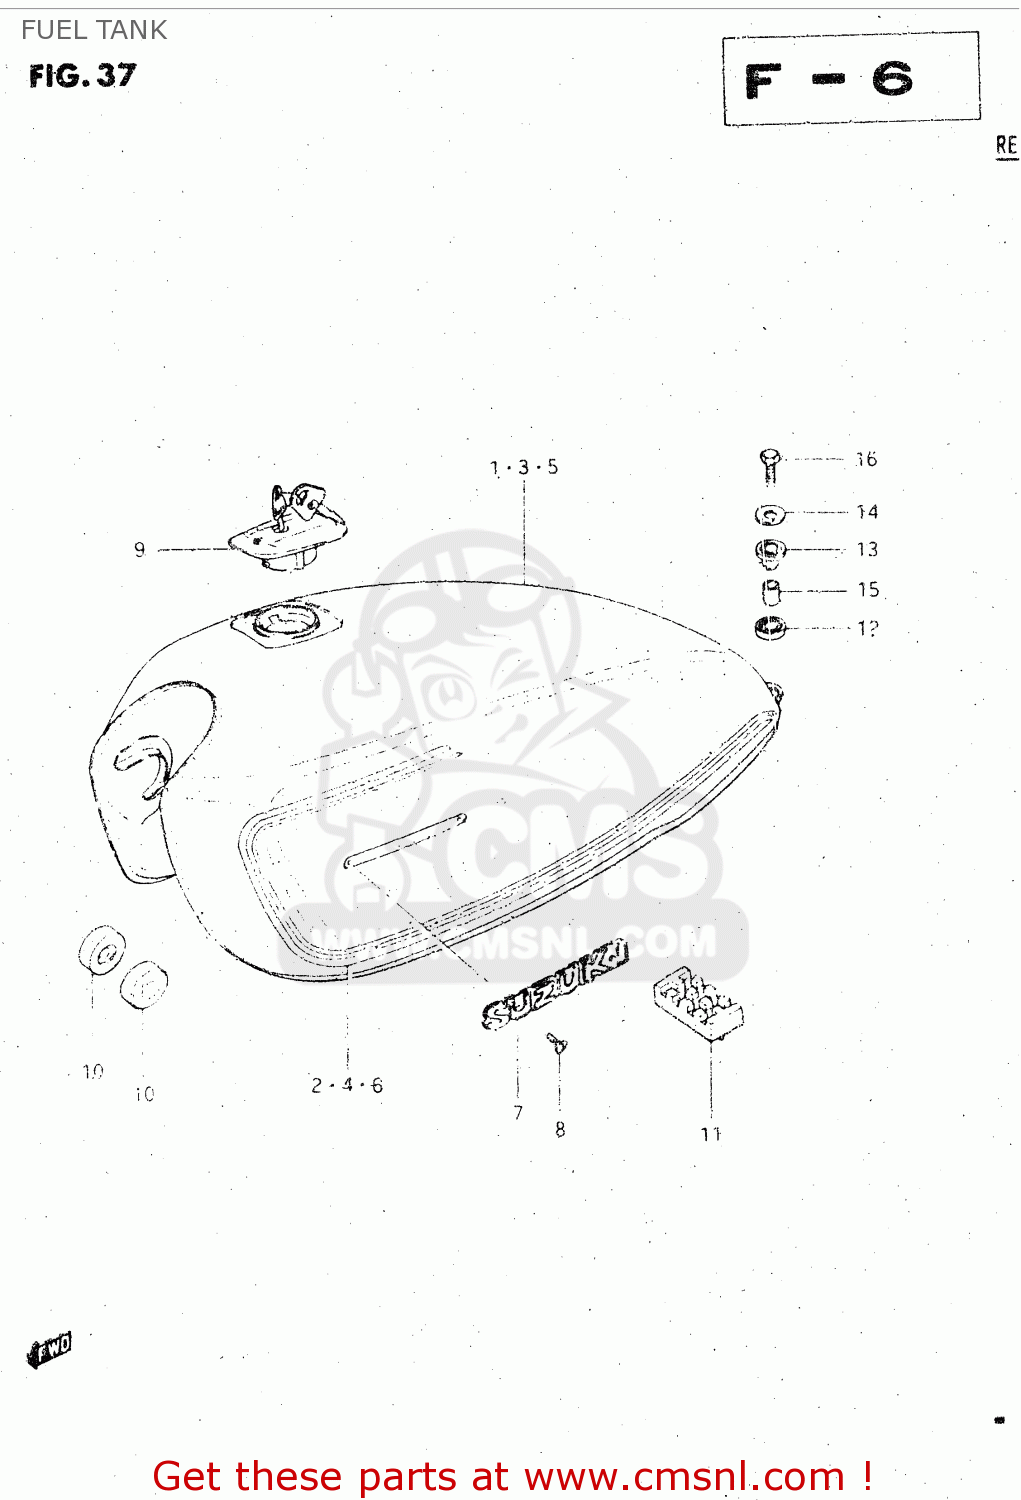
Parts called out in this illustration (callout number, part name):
1	TANK, FUEL (BLACK)
2	TAPE SET
3	TANK, FUEL (RED)
4	TAPE SET
5	TANK, FUEL (BLUE)
6	TAPE SET
7	EMBLEM,FUEL TANK
8	SCREW 3X6
9	CAP SET,FUEL TANK
10	CUSHION
11	CUSHION,FUEL TANK CTR
12	CUSHION
13	CUSHION
14	WASHER (6.5X24X1.6)
15	SPACER
16	BOLT
